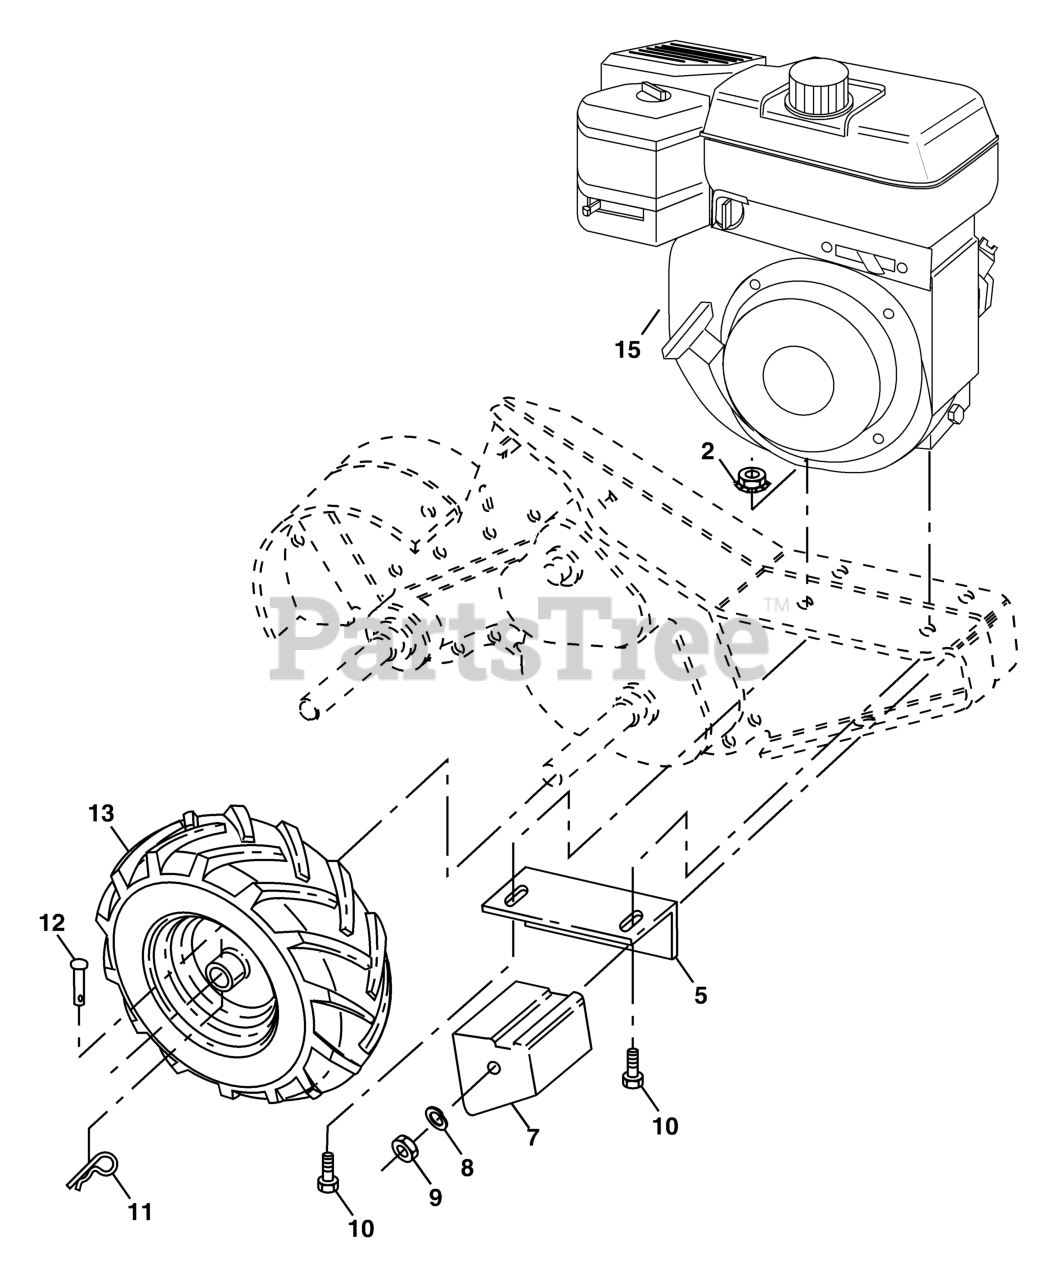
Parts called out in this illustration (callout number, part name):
2	LOCKNUT-FLANGE 5/16-18
5	DNO BRACKET RH CRT
7	COUNTERWEIGHT, RH
8	WASHER, LOCK 3/8
9	NUT.HEX.3/8-16UNC
10	BOLT
11	RETAINER M
12	RIVET,DRILLED
13	TIRE.16X4-8.CHEVRON.TILLER
13	RIM
13	VALVE STEM LT
